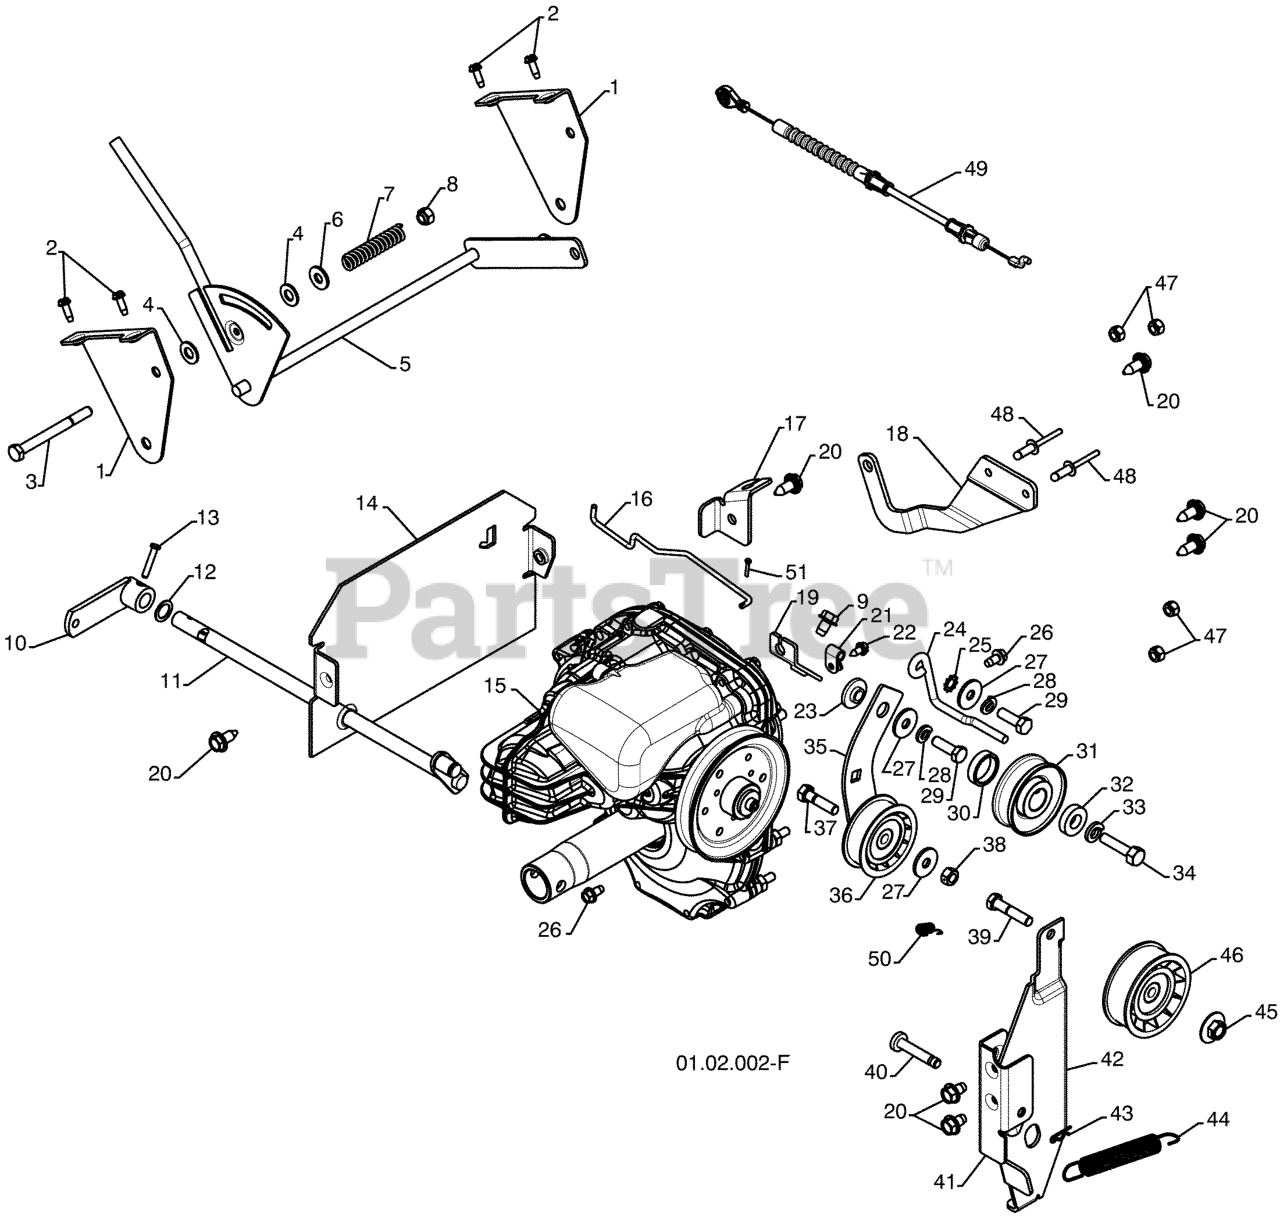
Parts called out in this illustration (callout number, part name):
1	BRACKET, SHIFT
2	SCREW #10-24 X 5/8
3	SCREW 5/16-18 X 3.25
4	WASHER, NYLON FRICTION
5	LEVER ASSEMBLY, SPEED CONTROL
6	WASHER.20X8.5
7	SRPING.FRICTION.HYDRO
8	NUT.71038.31-18.HEX.NYLOCK
9	BOLT 5/16-18 X .500
10	ARM.CONTROL.AUGER
11	SHAFT, AUGER CONTROL
12	THRUST WASHER
13	CLEVIS PIN
14	PLATE.REAR.HYDRO.ORANGE
15	TRANSMISSION.HYDRO.SNOW
16	ROD, BYPASS VALVE
17	BRACKET.CABLE.REAR.SNOW
18	ARM.CONTROL.HYDRO.SNOW
19	BRACKET, CABLE, FRONT
20	SELF-TAPPING SCREW 5/16-18X3/4
21	GUIDE CLIP PM
22	SCREW, SLOTTED HEX HEAD 1/8 X
23	RP BUSHING, IDLER PIVOT
24	GUIDE, BELT
25	WASHER EXT TOOTH LOCK 5/16
26	SCREW
27	STEEL WASHER
28	WASHER.LOCK.HVY.HLCL.SPR.5/16
30	SPACER.ENGINE.PULLEY
31	PULLEY,ENGINE TRACTION DRIVE
32	WASHER, FLAT 3/8
33	LOCKWASHER
34	SCREW, HEX HD 3/8-24 X 1-3/8
35	ARM, IDLER
36	PULLEY.W/SPACER.2.25
37	BOLT.5/16-18X1-1/4 FULL.THREAD
38	NUT.CENTERLOCK.5/16-
39	HEX BOLT
40	PIN, IDLER PIVOT
41	BRACKET, PIVOT, IDLER
42	ARM.IDLER.BRAKE.BLACK
43	RETAINER CLIP PM
44	SPRING, BRAKE
45	LOCKNUT 5/16-18
46	PULLEY.W/SPACER.2.75
47	LOCKNUT.NYLOC.1/4-20
48	RIVET.POP.1/4X.475
49	CABLE.DRIVE.CONTROL.SNOW
50	SPRING, TRACTION IDLER
51	RETAINER CLIP
